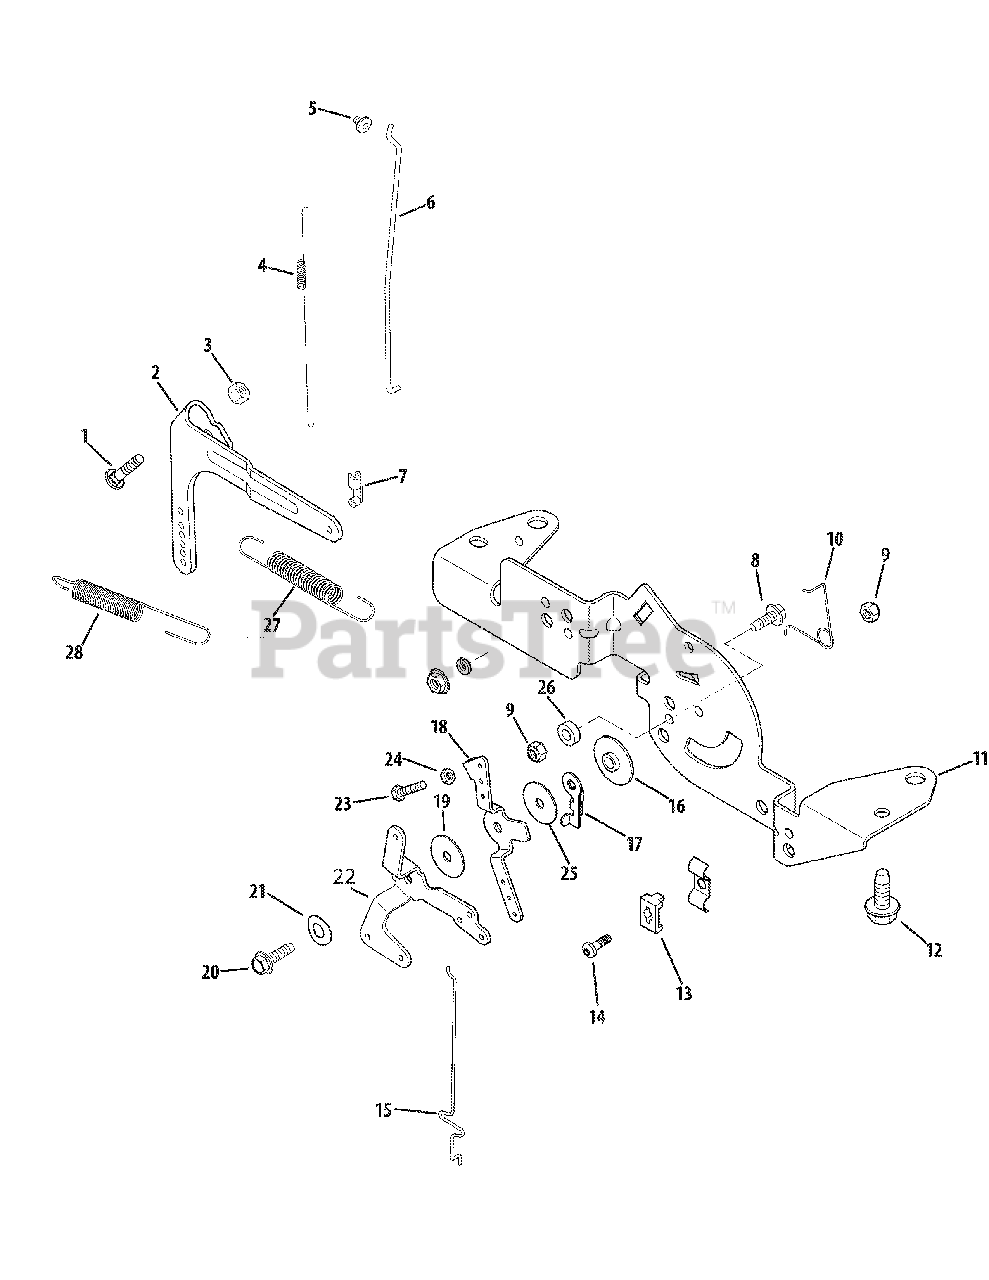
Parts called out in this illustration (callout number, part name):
1	Bolt, M6 x 1.0 x 25
2	Governor Lever
3	Flange Nut, M6 x 1.0
4	Linkage Spring
5	Linkage Retaining Bushing
6	Throttle Linkage
7	Throttle Linkage Bushing
8	Flange Screw, M5 x .8 x 16
9	Lock Nut, M5 x .8
10	Choke Return Spring
11	Control Bracket
12	Flange Screw, M6 x 1.0 x 1
13	Cable Clamp
14	Screw, M5 x .8 x 16
15	Choke Linkage
16	Control Assembly Spacer
17	Throttle Actuator Lever
18	Throttle Control Lever
19	Flat Washer, 5.5mm
20	Flange Screw, M5 x .8 x 20
21	Spring Washer, 1.4
23	Screw, M4 x .7 x 25
25	Flat Washer, 5mm
27	Governor Spring
28	Governor Spring
